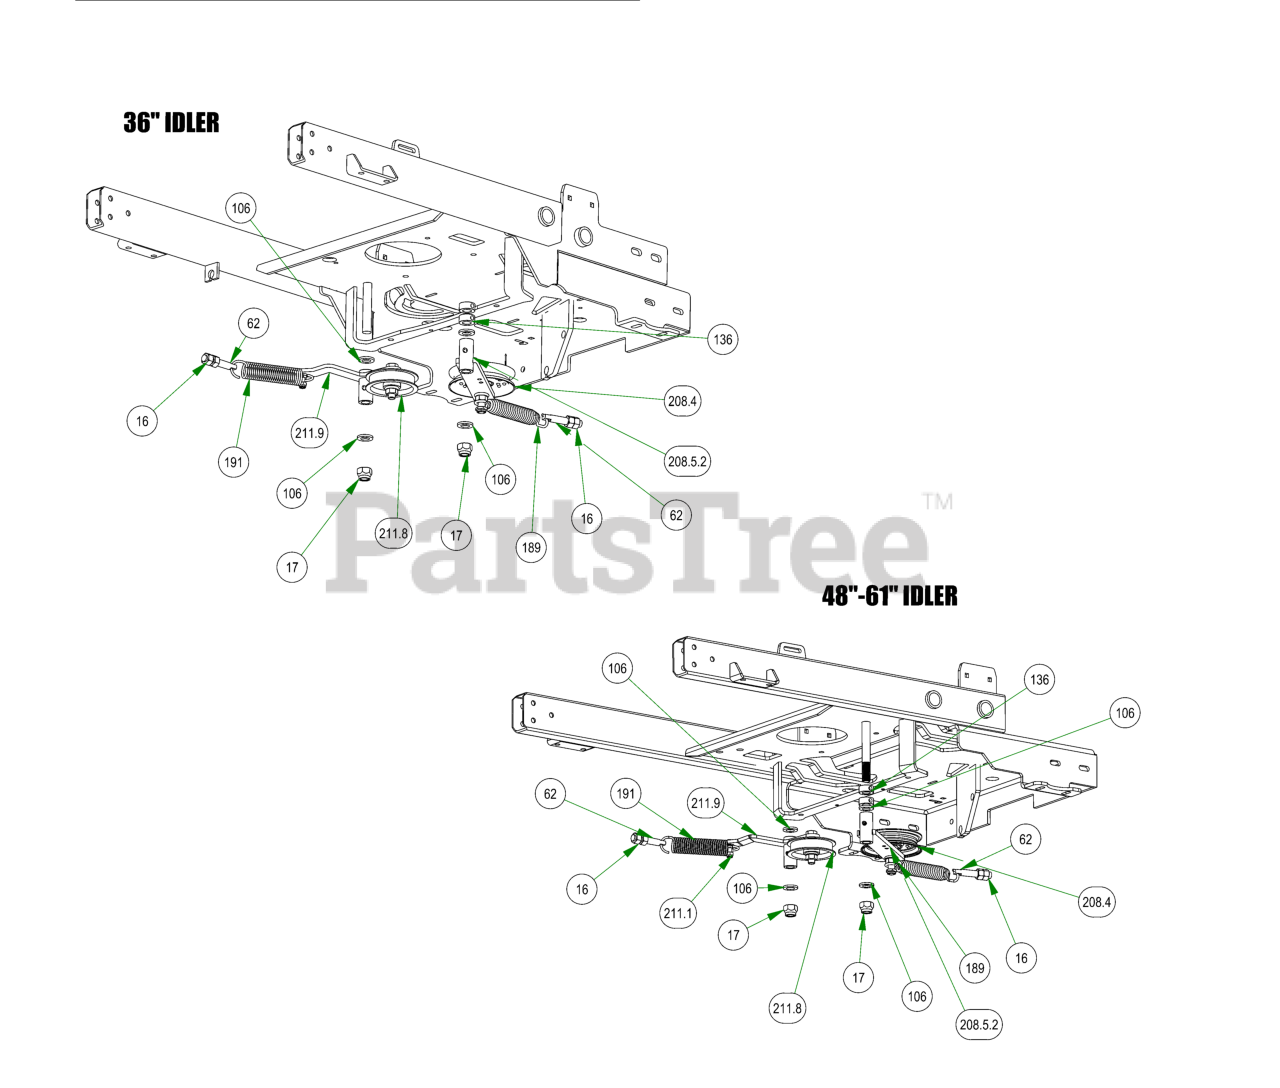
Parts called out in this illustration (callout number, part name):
16	1/2-13 HEX NUT ZINC
17	5/8-11 NYLON INSERT LOCKNUT ZINC
62	All Thread
70	1/2-13 NYLON INSERT JAM LOCKNUT ZINC
106	.635 ID X 1.120 OD X .140 THICK FLAT WASHER NYLON
136	5/8 SOLID SHAFT COLLAR (W/1 SET SCREW) ZINC
189	Deck Idler Spring
191	Deck spring big diameter
208	2019 Stand On Idler Assembly
208.1	1/2-13 NYLON INSERT FLANGE LOCKNUT ZINC
208.2	1/2-13 X 2-3/4 HEX CAP SCREW (GR.5) ZINC
208.3	1/2 SOLID SHAFT COLLAR (W/1 SET SCREW) ZINC
208.4	4 3/4 Idler Pulley - ABFI-76
208.5	Deck Idler
208.5.1	1/4-28 Grease Fitting
208.5.2	DECK IDLER LEVER
208.5.3	Idler Retainer
211	2020 36" Stand-On Drive Belt Pulley Assembly
211.1	5/16-18 NYL INS L/N ZC
211.2	1/2-13 NYLON INSERT FLANGE LOCKNUT ZINC
211.3	5/16-18 HEX SERRATED FLANGE NUT HARD/ZINC
211.4	5/16-18 X 1-1/4 CARRIAGE BOLT ZINC
211.5	1/2-13 X 2-1/4 HEX CAP SCREW (GR.5) ZINC
211.6	1/4" Press in Grease Fitting
211.7	1/2 SOLID SHAFT COLLAR (W/1 SET SCREW) ZINC
211.8	3.25 Flat Idler Pulley
211.9	36 Pump Idler Arm Weldment
265	2019 Stand On Frame
266	2020 36" Stand On Frame
